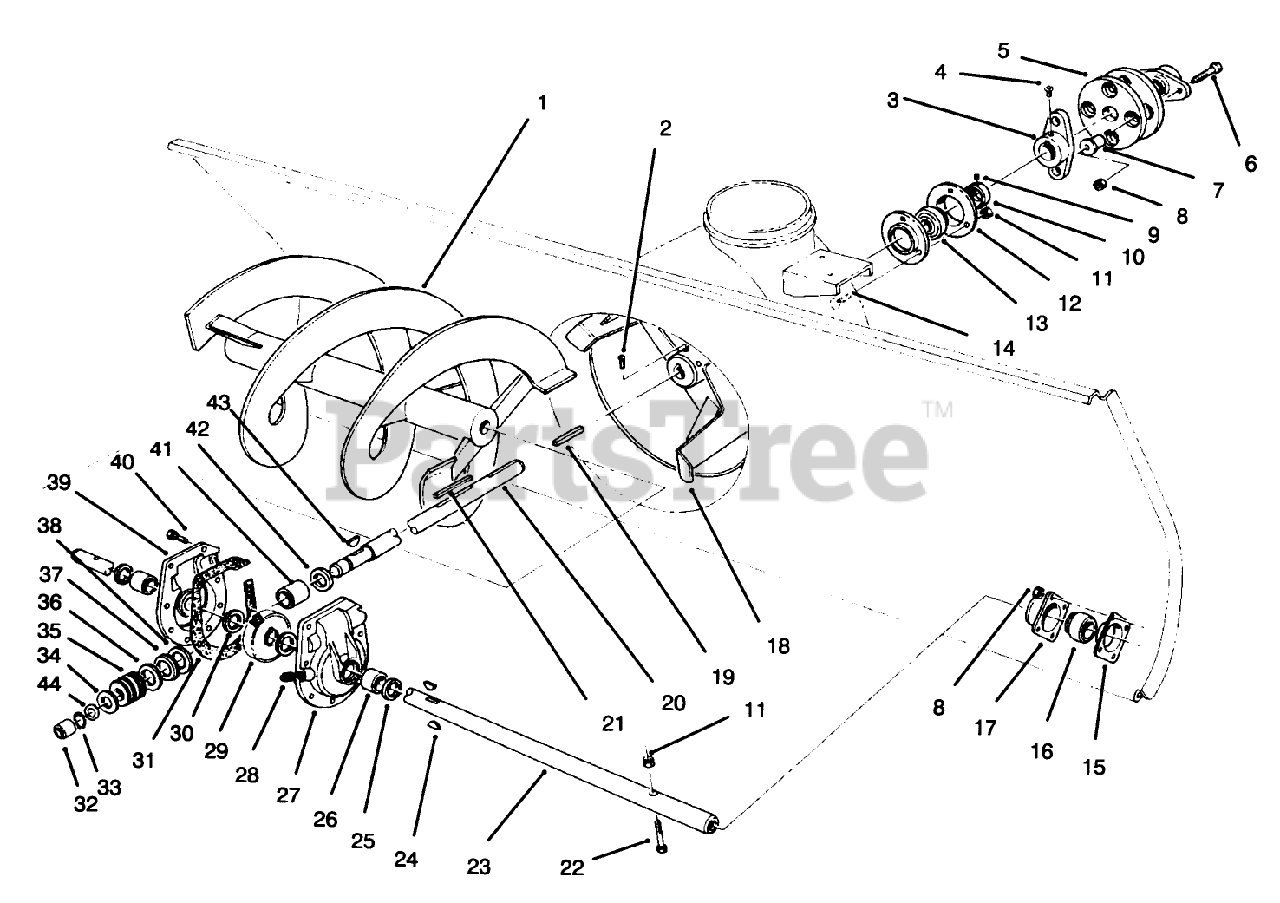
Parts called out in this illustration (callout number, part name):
1	Auger RH
2	SCREW-SET, SQH
3	HUB WA (KEY) R
4	SCREW-SET
5	COUPLING-RUBBER
6	SCREW-HH
7	SPACER-COUPLING, RUBBER
8	NUT-LOCK, NI
9	SCREW-HSH
10	EXT LOCKING COLLAR
11	NUT-LOCK, NI
12	BRG FLANGE
13	BALL BRG W/COLLAR
14	BOLT-CARR
15	BEARING-FLANGE, REAR
16	BEARING
17	BEARING-FLANGE, FRONT
18	IMPELLER ASM
19	KEY-SQUARE
20	IMPELLER SHAFT
22	SCREW-HH
23	SHAFT-AUGER
24	KEY-WOODRUFF
25	SEAL-OIL
26	BUSHING
27	Gear Case & Bushing Assy. (Incl. Ref. #25 & 26)
28	PLUG-PIPE, SQH
29	GEAR-WORM, 27T
30	WASHER-THRUST
31	GASKET-GEAR BOX
32	BUSHING
33	Ring-Snap
34	WASHER-THRUST
36	THRUST-WASHER
37	BEARING-THRUST
38	WASHER-THRUST
39	Gear Case & Bushing Assy. (Incl. Ref. #25 & 26)
40	SCREW-TAPTITE
41	BUSHING-SPECIAL
42	RING-QUAD
43	KEY-WOODRUFF
44	WASHER-SHIM
